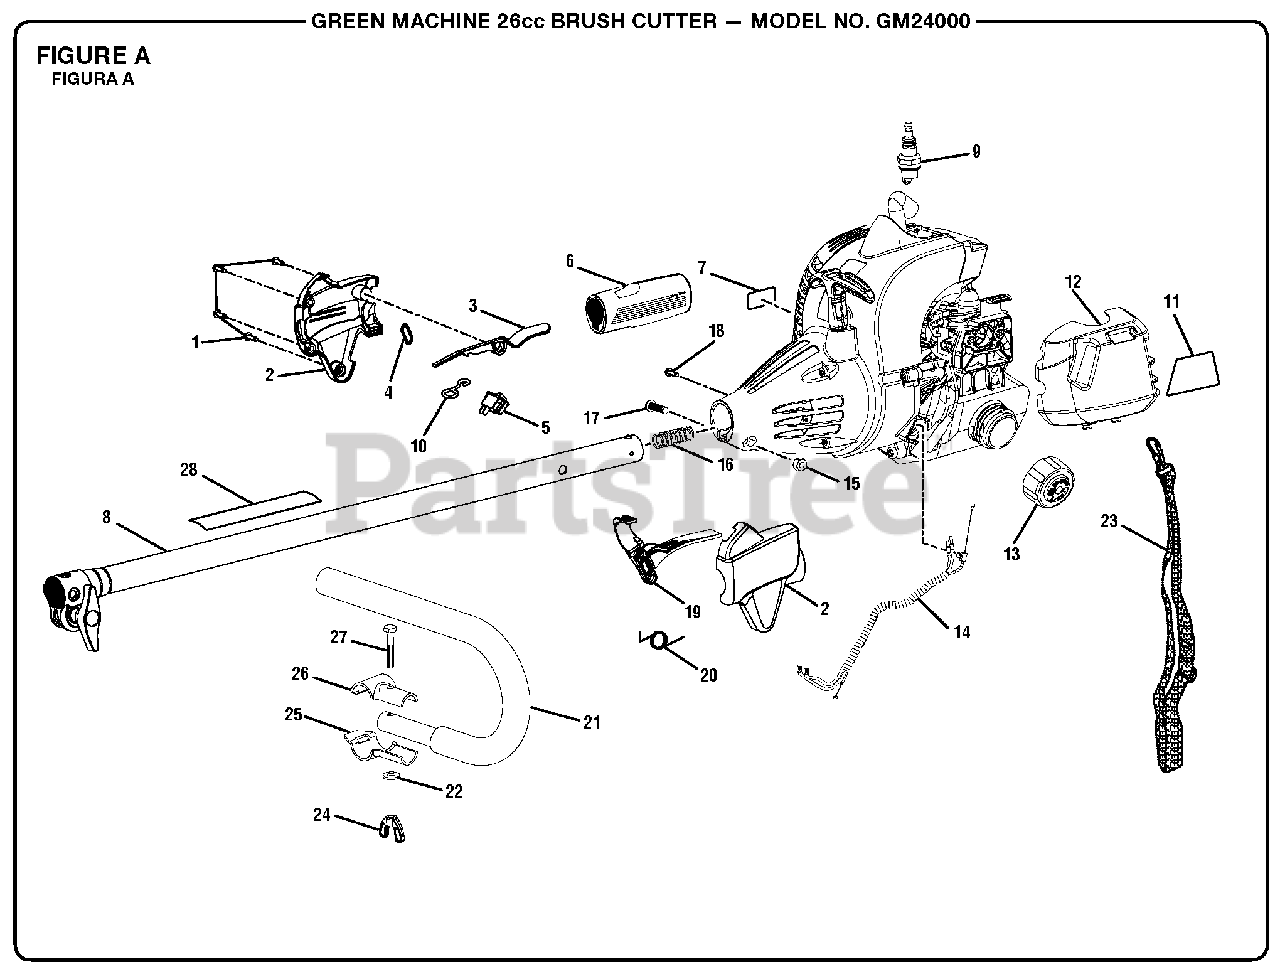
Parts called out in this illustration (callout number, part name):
1	Screw (M4 x 20 mm)
2	Control Handle Assembly
3	Trigger Lock
4	Strap Hanger
5	Switch (Momentary Contact)
6	Rear Handle
7	Combustion Warning Label
8	Upper Boom Assembly
9	Spark Plug (Champion RCJ6Y)
10	Throttle Spring
11	Starting Label
12	Air Box Cover
13	Fuel Cap Assembly (1.5 in. Diameter)
14	Throttle and Lead Assembly
15	Hex Nut (M6)
16	Compression Spring
17	Bolt (M6 x 20 mm)
18	Screw (8-16 x 5/16 in., Torx T.F.)
19	Throttle Trigger
21	"J" Handle and Grip
23	Shoulder Harness
24	Wing Nut (1/4-20)
25	Bottom "J" Handle Clamp
26	Top "J" Handle Clamp
27	Bolt (1/4-20 x 1-1/2 in., Hex Hd.)
28	Warning Decal
